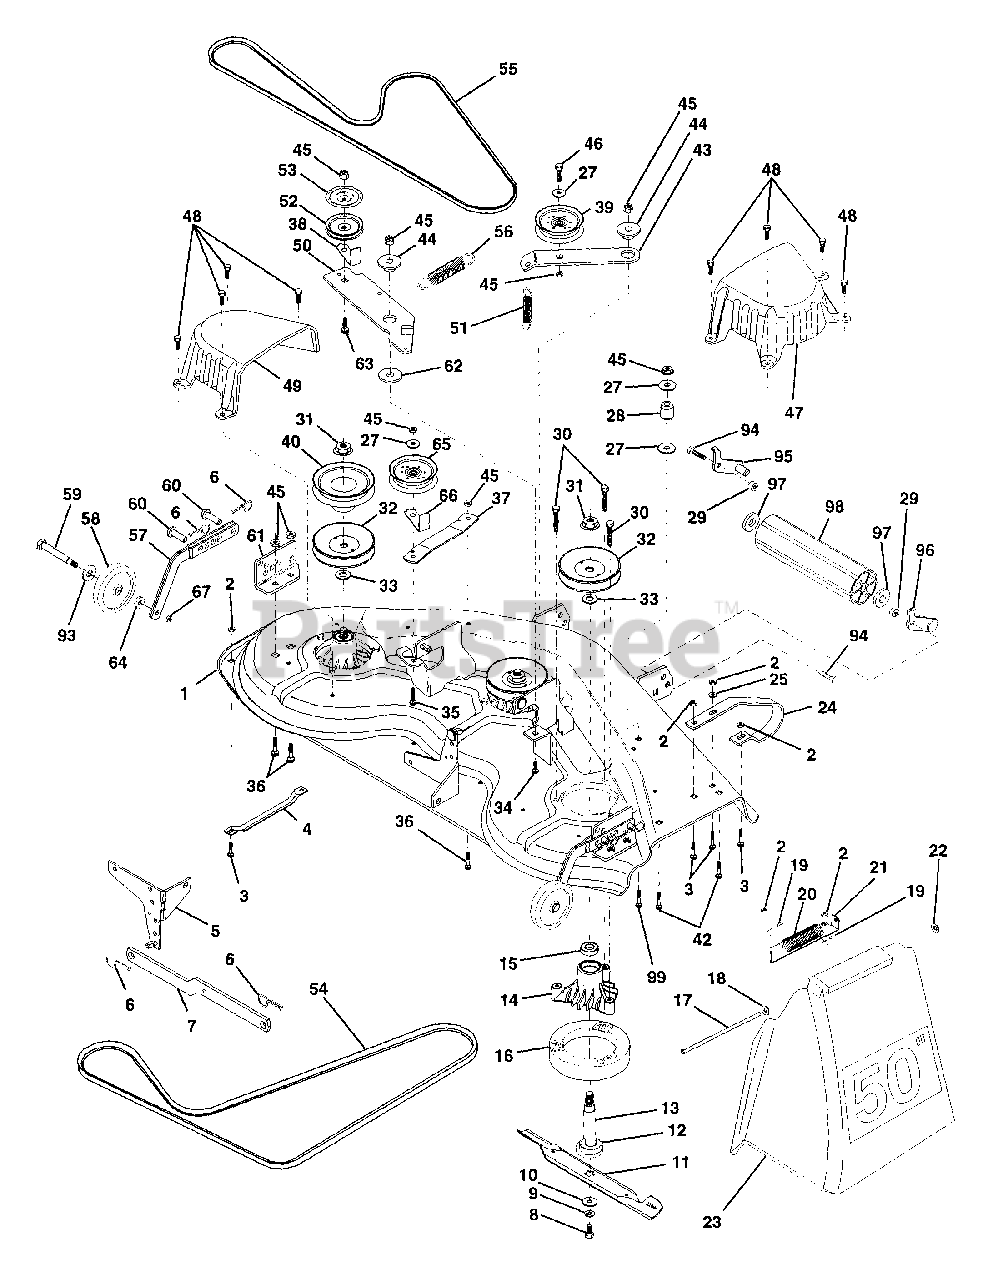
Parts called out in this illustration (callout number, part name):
1	Deck Asm., Mower 50" Vented
2	Nut, Crownlock 5/16-18
3	Bolt, Carriage 5/16-18 x 3/4
4	Runner, Mower LH
5	Bracket Asm., Sway Bar
6	Retainer, Spring
7	Arm Suspension, Rear
8	Bolt 3/8-24 x 1.25 Gr. 8 Patched
9	Washer, Lock Hvy 3/8 Unplated
10	Washer, Hard Blade Mower Vented
11	Blade (3 Req.)
12	Bearing, Ball #6204 (Mandrel)
13	Shaft Asm., W/Lower Brg
14	Housing, Mandrel 50" Vent
15	Bearing, Ball Mandrel
16	Stripper, Mower Vented
17	Rod, Hinge
18	Washer 11/32 x 5/8 x 16 Ga.
19	Cap, Sleeve
20	Spring, Torsion Deflector
21	Bracket, Deflector
23	Shield, Deflector Mower
24	Runner, RH
25	Washer 11/32 x 3/4 x 16 Ga.
27	Washer 13/32 x 13/16 x 16 Ga.
28	Spacer, Spring Stop Idler
29	Nut, Lock Hex W/Wsh 3/8-16 Unc
30	Screw Thdrol Hex Head
31	Nut, Flg Top Lock Cntr 9/16
32	Pulley, Mandrel
33	Washer, Spacer Mower Vented
34	Bolt, Carriage 3/8-16 x 1-1/4
35	Bolt, Carriage 3/8-16 x 2
36	Bolt, Carriage 3/8-16 x 1 Gr. 5
37	Stiffener, Arm Idler
38	Keeper, Belt Idler
39	Pulley, Idler Flat
40	Pulley, Driven
42	Bolt, Carriage 5/16-18 Unc x 3/4
43	Arm, Idler Secondary
44	Spacer, Retainer
45	Nut, Crownlock 3/8-16 Unc
46	Bolt, Fin Hex 3/8-16 Unc x 1-3/4
47	Cover, Mandrel RH
48	Screw, Thd Roll 1/4-20 x 5/8
49	Cover, Mandrel LH
50	Arm, Idler Primary
51	Spring, Secondary
52	Pulley, Idler V Groove
53	Shield, Idler
54	V-Belt, Mower Primary
55	V-Belt, Mower Secondary
56	Spring, Primary
57	Bar Asm., Wheel Gauge
58	Wheel, Gauge
59	Bolt, Shoulder
60	Pin, Clevis
61	Bracket, Wheel Gauge
62	Washer Hardened
63	Bolt Carriage 3/8-16 x 1-1/2
64	Washer 3/8 x 7/8 x 14 Ga.
65	Pulley Idler Flat Mower
66	Keeper, Belt Idler 50" Vent
67	Nut, Center Lock 3/8-16
93	Washer 17/32 x 15/16 x 12 Ga.
94	Bolt, Fin Hex 3/8-16 x 1
95	Bracket, Asm. Noseroller LH
96	Bracket, Asm. Noseroller RH
97	Washer 17/32 x 7/8 x 16 Ga.
98	Roller, Nose
99	Bolt, Carriage 3/8-16 x 1-3/4 Gr. 5
